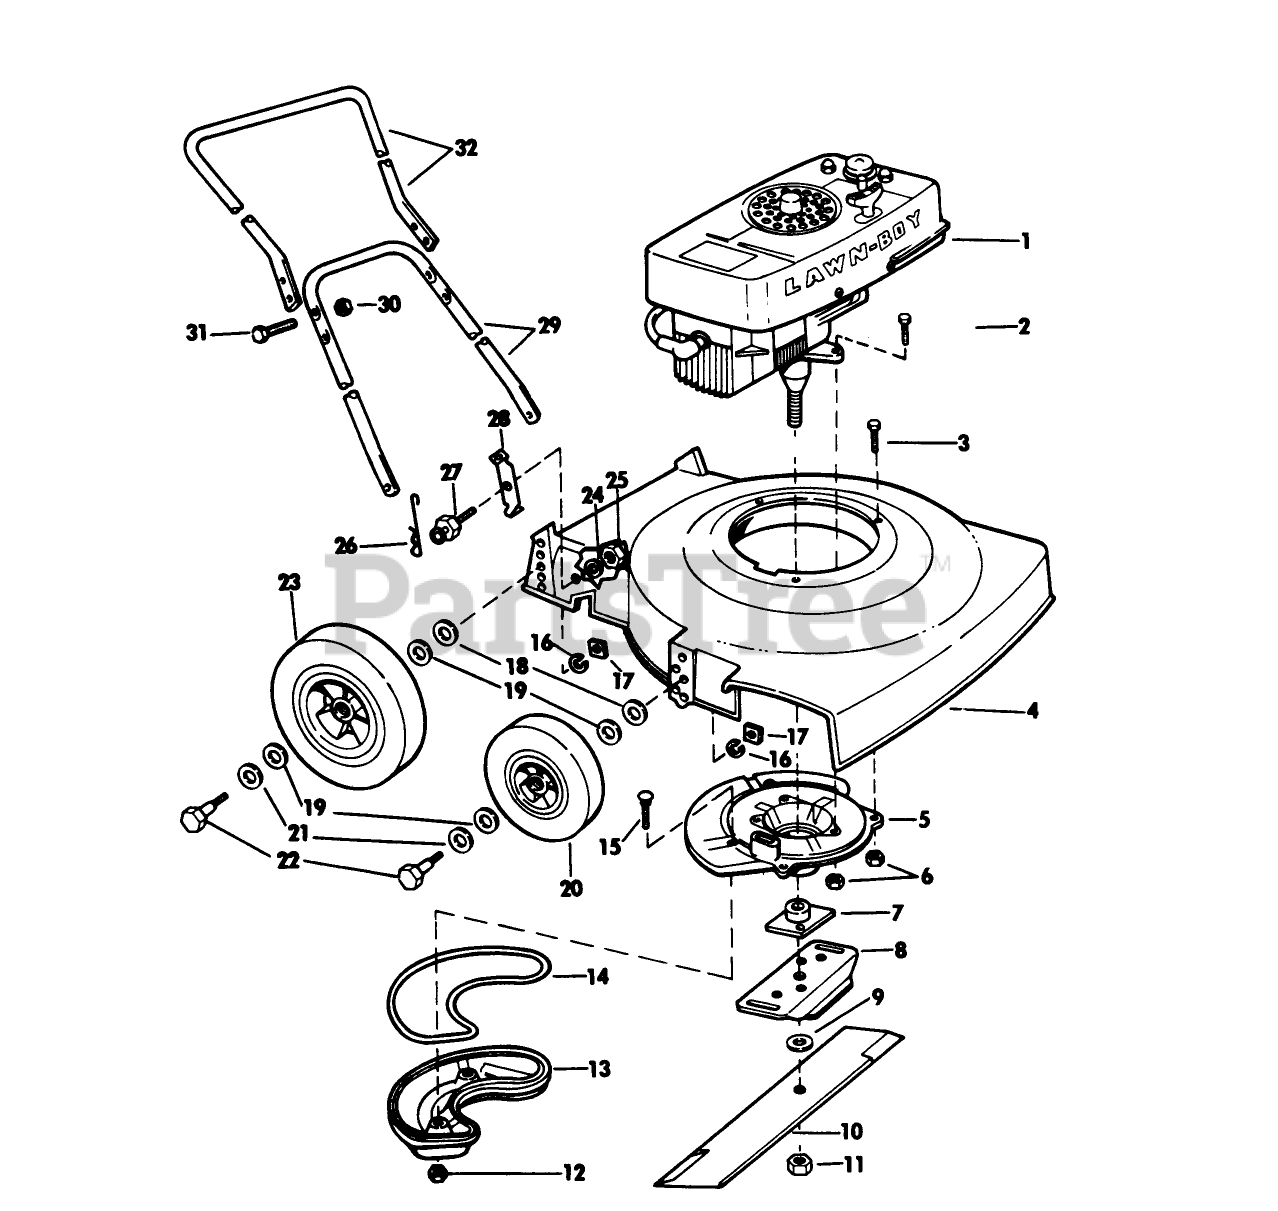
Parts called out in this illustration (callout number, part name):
3	SCREW
6	NUT
7	PLATE AND COLLAR ASM
9	WASHER
11	NUT-BLADE
12	LOCKNUT E
16	WASHER, LOCK
17	NUT
18	WASHER WROUGHT
19	WASHER
20	WHEEL & TIRE KIT
21	SPACER
22	BOLT
24	Lockwasher
31	SCREW
